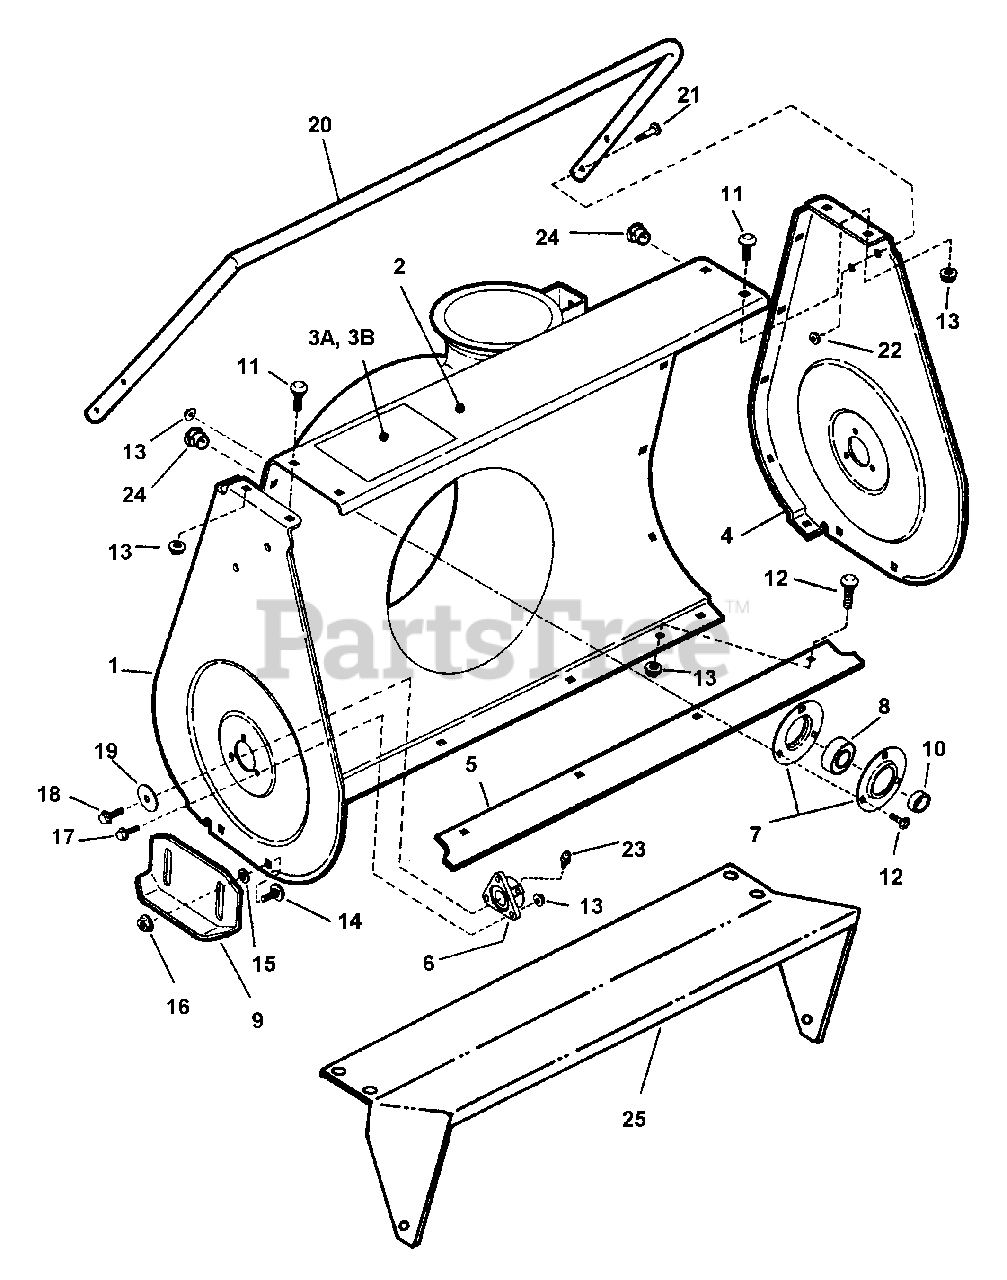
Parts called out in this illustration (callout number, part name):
1	PLATE, Right Side
2	ASSEMBLY, 22" Blower Housing
3A	DECAL, Foot Danger
3B	DECAL, Danger (Collector)
4	PLATE, Left Side
5	BLADE, Scraper
6	BEARING, Auger Shaft
7	HOUSING, Bearing
8	BEARING, Ball
9	SHOE, Skid
10	SPACER, 3/4 x 1/4 x 1"
11	SCREW, 1/4-20 x 5/8" Self-Tapping
12	BOLT, 1/4-20 x 5/8" Square Neck Carriage, Grade 5
13	NUT, 1/4-20 Hex Flange Lock
14	BOLT, 5/16-18 x 5/8" Short Neck Carriage, Grade 5
15	WASHER, 5/16 Flat
16	NUT, 5/16-18 Hex Flange Lock
17	BOLT, 1/4-20 x 3/4" Hex Flange Lock, Grade 5
18	SCREW, 5/16-18 x 5/8" Hex Washer Self-Tap
19	WASHER, 21/64" Flat
20	DRIFT-CUTTER
21	SCREW, 1/4-20 x 1" Hex Head Cap, Grade 5
22	NUT, 1/4-20 Hex Center Lock
23	FITTING, Lube (Press fit for .187 hole-no ball)
24	PLUG, Dome 3/16" Diameter
25	ADAPTER, Housing
